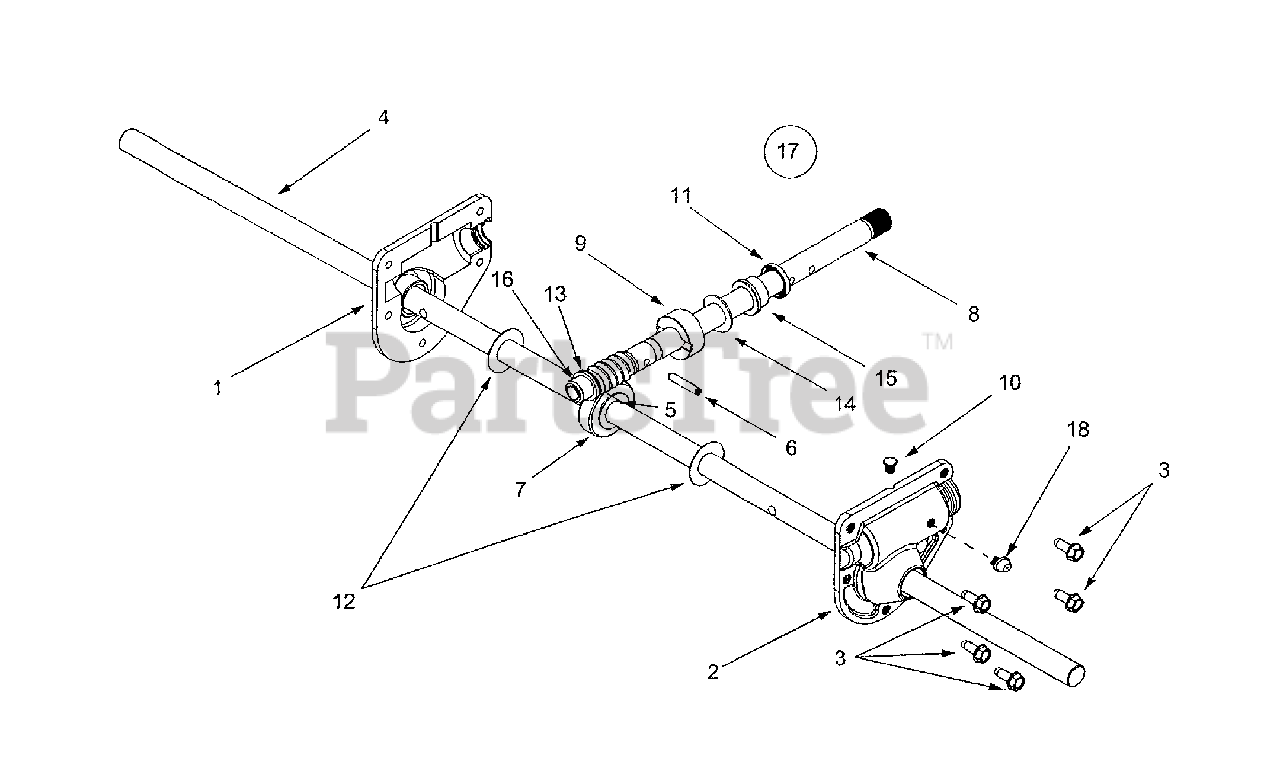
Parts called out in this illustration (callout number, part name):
1	RH Housing
2	LH Housing w/Fitting
3	Self Tapping Screw, 1/4-20 x .75
4	Spiral Axle, 22"
5	Hi-Pro Key, 3/16 x 5/8
6	Spring Spirol Pin, .25 x 1.25
7	Worm Gear, 20-tooth
8	Worm Shaft
9	Thrust Collar
10	Grease Plug
11	Grease Seal
12	Flat Washer, .76 x 1.5 x .030
13	Flat Washer, .508 x 1.0 x .020
14	Flat Washer, .76 x 1.5 x .060
15	Flange Bearing, .75 x 1.0 x .59
16	Flange Bearing, .503 ID x .75 OD
17	Gear Assy Complete, 22"
18	Grease Fitting, 3/16" Drive
